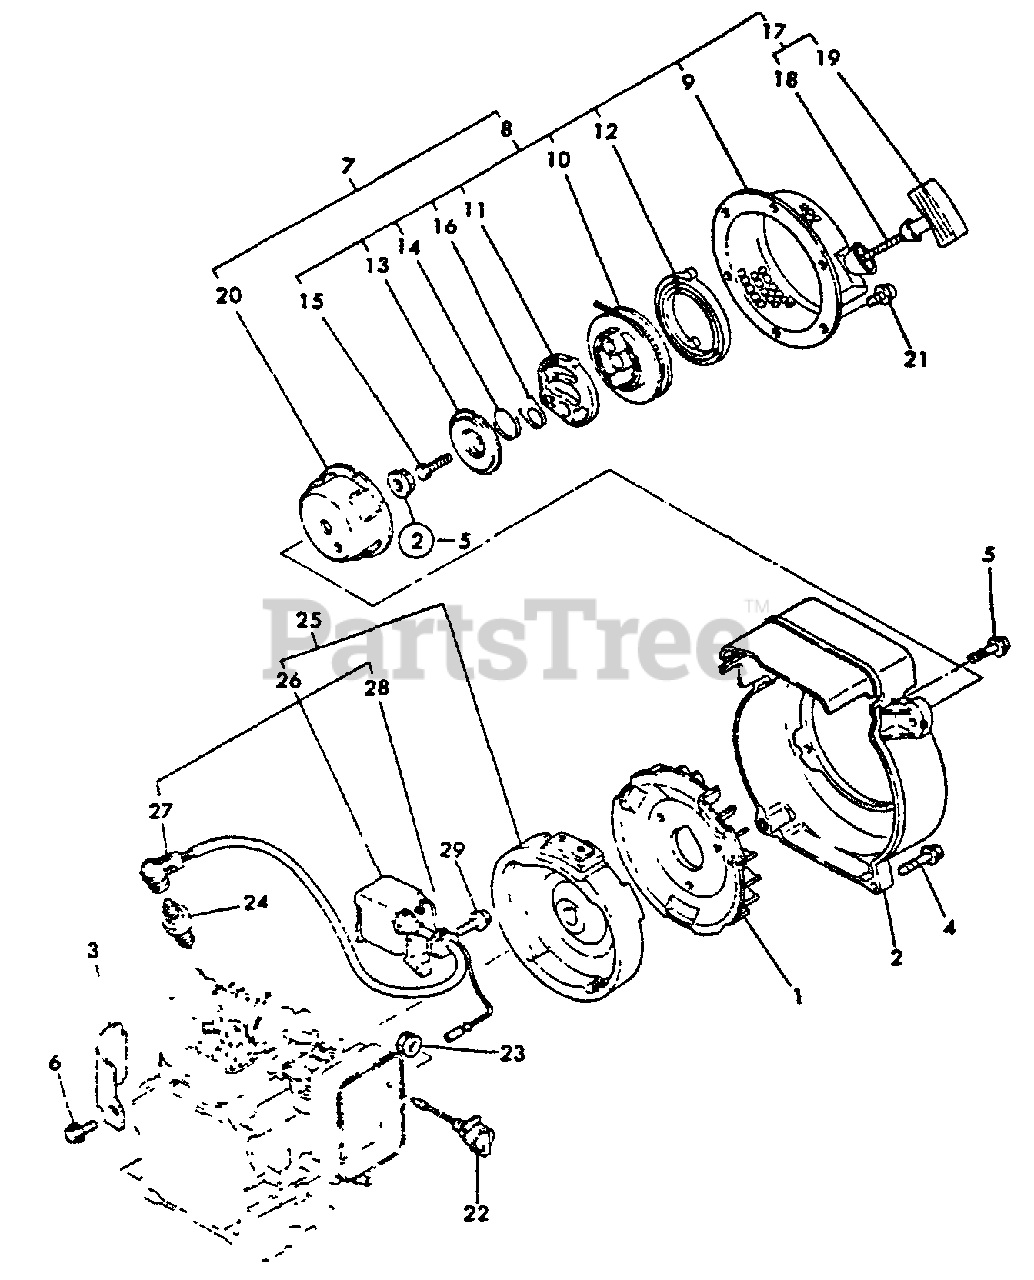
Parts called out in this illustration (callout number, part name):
1	FAN
2	COVER, FAN
3	SHIELD, CYLINDER
4	BOLT - 6×30
5	BOLT - 6×30
6	BOLT - 6×8 -- PLATED
7	STARTER ASSY
8	STARTER ASSY, RECOIL
9	STARTER CASE ASSY
10	PULLEY
11	RATCHET
12	SPRING
13	PLATE, FRICTION
14	SPRING, FRICTION
15	BOLT
16	SPRING, RETURN
17	ROPE ASSY
18	ROPE
19	GRIP, STARTER
20	PULLEY, STARTER
21	BOLT - 6×8 -- PLATED
22	IGNITION SWITCH ASSY
23	U-NUT M8
24	SPARK PLUG - BPM-8Y
25	FLYWHEEL MAGNETO ASSY
26	COIL, IGNITION
27	CAP, PLUG
28	GROMMET
29	BOLT - 6×30
